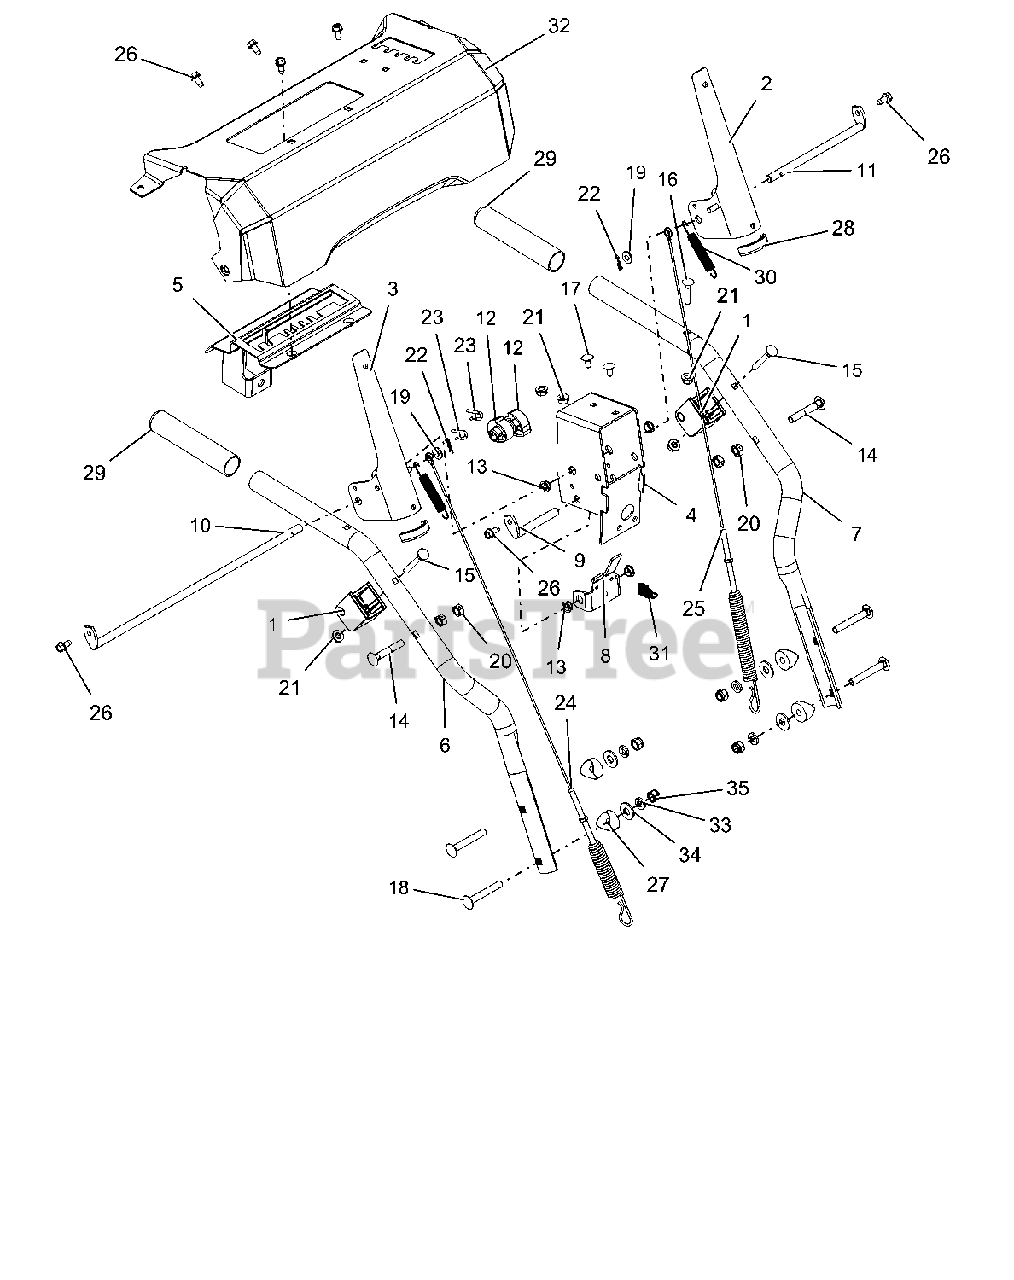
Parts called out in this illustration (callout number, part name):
1	BLOCK, CLUTCH PADDLE
2	LEVER, CLUTCH-LH
3	LEVER, CLUTCH-RH
4	WELDMENT, BRACKET INTERLOCK
5	WELDMENT, DETENT PLATE-COMPACT
6	HANDLEBAR, UPPER - RH
7	HANDLEBAR, UPPER - LH
8	BRACKET, INTERLOCK ARM
9	ROD, PIVOT - INTERLOCK
10	ROD, PADDLE MOUNT - LONG
11	ROD, PADDLE MOUNT - SHORT
12	CAM, INTERLOCK
13	BUSHING, POLYLINER-.38 SNAPIN
14	BLT-RDHDXLSQNK .31-18X2.0 G5YZ
15	BLT-RDHDXLSQNK .25-20X2.0 G5YZ
16	BLT-RDHDXLSQNK.25-20X1.25 G5ZC
17	@BLT-RDHDSQNK .25-20X.50 G5YZ
18	@BLT-RDHDSQNK .31-18X2.25 G5YZ
19	@WSHR-FL-STL.281X.62X.065 YWZC
20	@NUT-LK-CTR .31-18 YWZC
21	@NUT-LK-TOP-FLG .25-20 YWZC
22	PIN-HAIR INT .06X.18X.77
23	PIN, SPRING CLIP
24	CABLE, AUGER (DELUXE & PRO)
25	CABLE, UPPER TRACTION
26	SCR-TAP .25-20X.50 HWH TR YWZ
27	SPACER, HANDLEBAR
28	EDGING, CLUTCH PADDLE - 2.00"
29	GRIP,HANDLE-GRAY
30	SPRING, EXTENSION
31	SPRING-EXT .047X.438X1.45
32	CONTROL PANEL W/DECAL, BRUSH
33	WSHR-LK .312X.097 HVY YWZC
34	@WSHR-FL-STL.38X.875X.083 YWZC
35	@NUT-LK-NYL .312-18 YWZC
